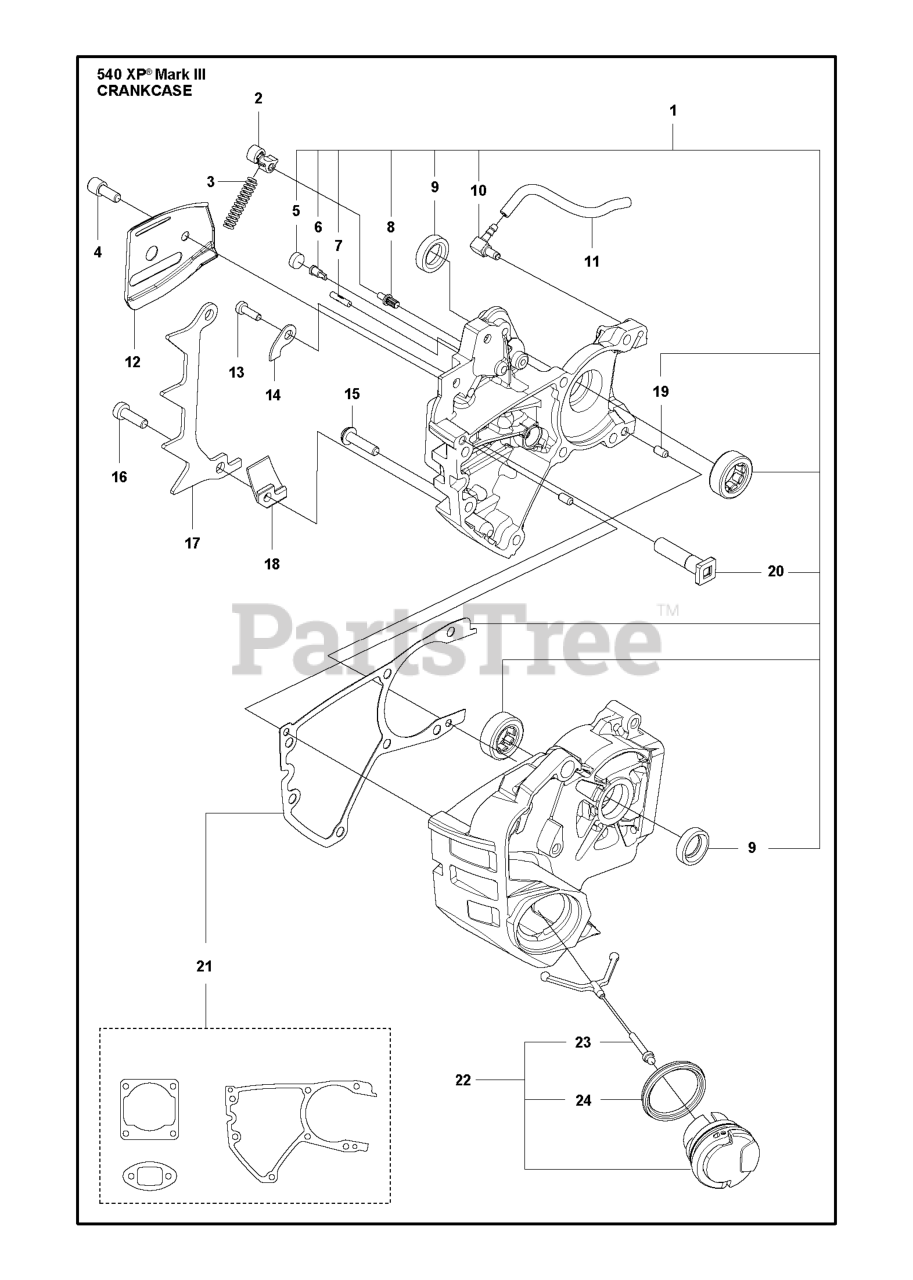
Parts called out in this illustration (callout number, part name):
3	LOCK SPRING
5	SEAL Z285021250
6	AIR CONTROL BREATHER
9	RADIAL SEAL
10	ELBOW FITTING
13	SCREW
15	SCREW
16	SCREW HEXABOULAR SLOTTED SOCKE
18	CHAIN CATCHER
22	TANK CAP ASSY
